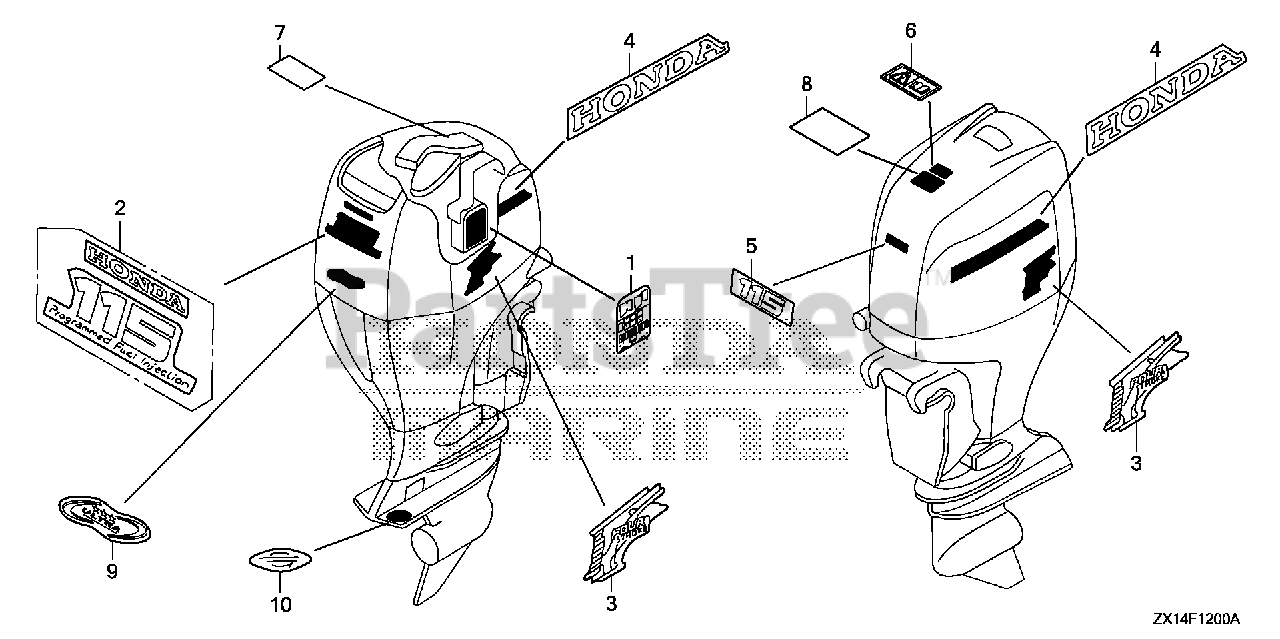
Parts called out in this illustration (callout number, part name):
1	LABEL, FUSE
2	MARK, RR. (115)
3	MARK, SIDE
4	MARK, SIDE STRIPE
5	MARK, FR. EMBLEM (BF115)
7	LABEL, OIL CAUTION (E)
8	LABEL, OPERATOR CAUTION (ENGLISH)
8	LABEL, WARNING OPERATOR
